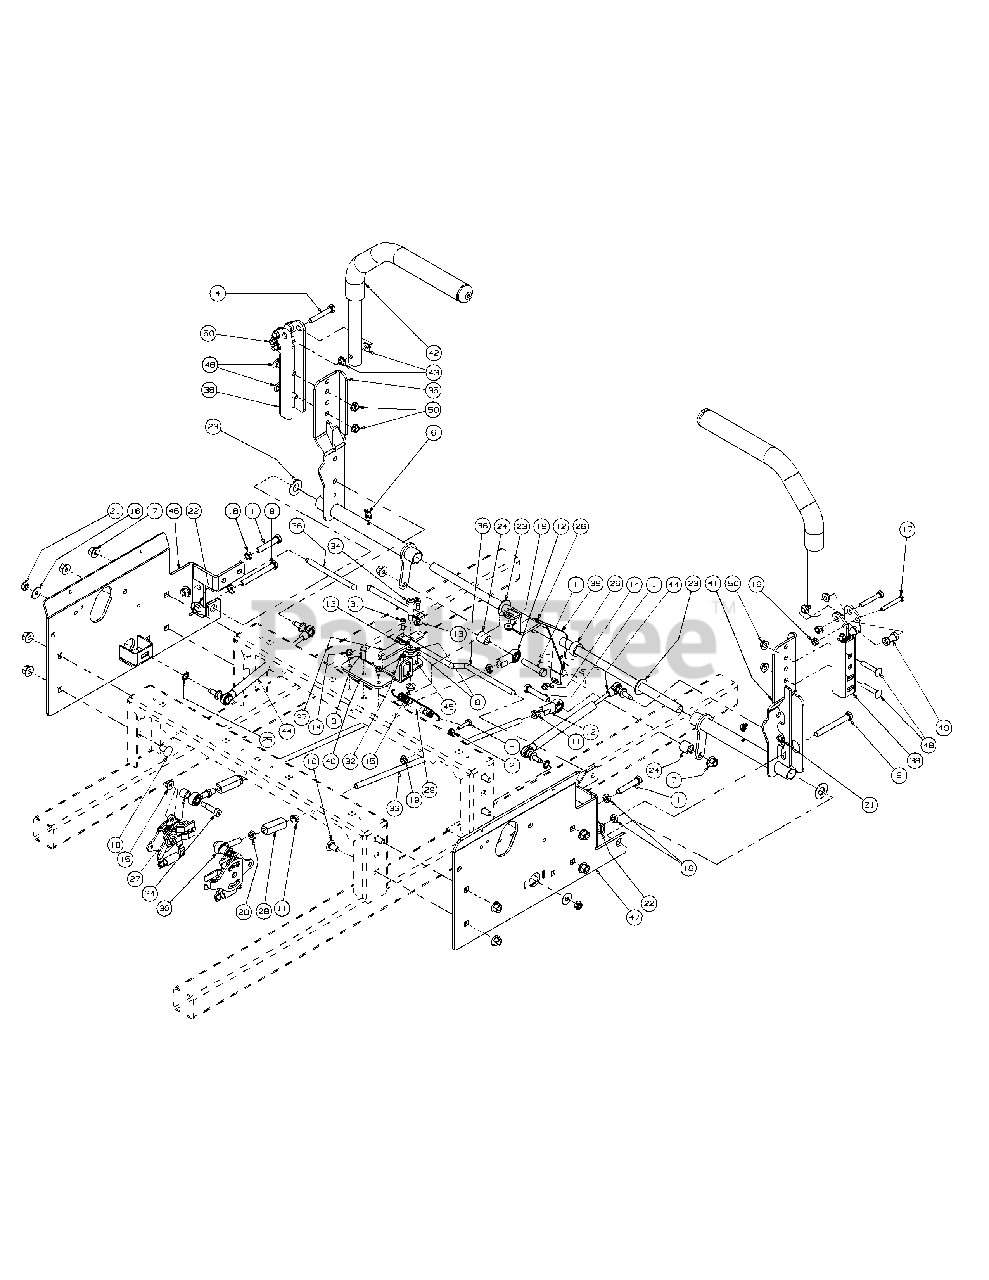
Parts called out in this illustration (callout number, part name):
1	Hex Cap Screw, 3/8-16 x 2.00
2	Hex Nut, 1/4-20
3	Hex Cap Screw, 1/4-20, .75
4	Hex Cap Screw, 5/16-18 x 2.00
5	HHCS, 1/4-20 x 1.00
6	Grease Fitting, 1/4-28, 45 degree
7	Hex Nut, 3/8-16, Lock Flange
8	Washer, 3/8, SS
9	Hex Cap Screw, 3/8-16 x 3.50
10	Carriage Bolt, 3/8-16 x .75
11	Hex Jam Nut, 3/8-24
12	B/Joint, 3/8-24, Right Hand Female
13	Flat Washer, 1.4 x .630 x .0515
14	Screw, TT, 1/4-20, 0.5, Hex Index Washer
15	Nut, Lock, HexFlange, 5/16-18
16	Belle Washer, .325 x .930 x .045
17	Hex Cap Screw, 1/4-20 x 2.00
18	Nut, 3/8-16, Jam
19	Hex Flange Lock Nut, 1/4-20
20	Nut, 3/8-24, Jam, LH Third
21	Nut, Hex, Center Lock, M8
22	U-Nut, 3/8-16, .75
23	Flat Washer, 5/8 Nylon
24	Spacer, .385 ID x .75 OD x .875
25	External Washer, 3/8
26	Shaft Collar
27	Spacer, .625 OD x .385 ID x 1/2
28	Turnbuckle
29	Extension Spring, .53 OD x 4.75
30	B/Joint, 3/8-24, Left Hand Female
31	Shoulder Bolt, 1/4 x 1/4
32	Nut w/ Star Washer, 10-24
33	Control Rod, 3/8 x 17.312
34	Screw, Shoulder Control Rod
36	Brake/Control Rod
37	Lapbar Control Arm
38	Lapbar Pivot Bracket
39	Lapbar Control Shaft Assembly
40	Lapbar/Brake Control Mounting Bracket
42	Lapbar Assembly includes:
42	Grip, 1.0
43	Bushing, .310 x .172 x .688 x .06
44	Cylinder Return to Neutral
45	Spacer, .405 ID x 1.0 OD x .72
46	Side Panel, Control, Left
47	Side Panel, Control, Right
48	Carriage Bolt, 5/16-18 x 1.75
49	Spacer, .251 ID x .38 OD x 1.13 LG
50	Nut, Lock, HexFlange, 5/16-18
